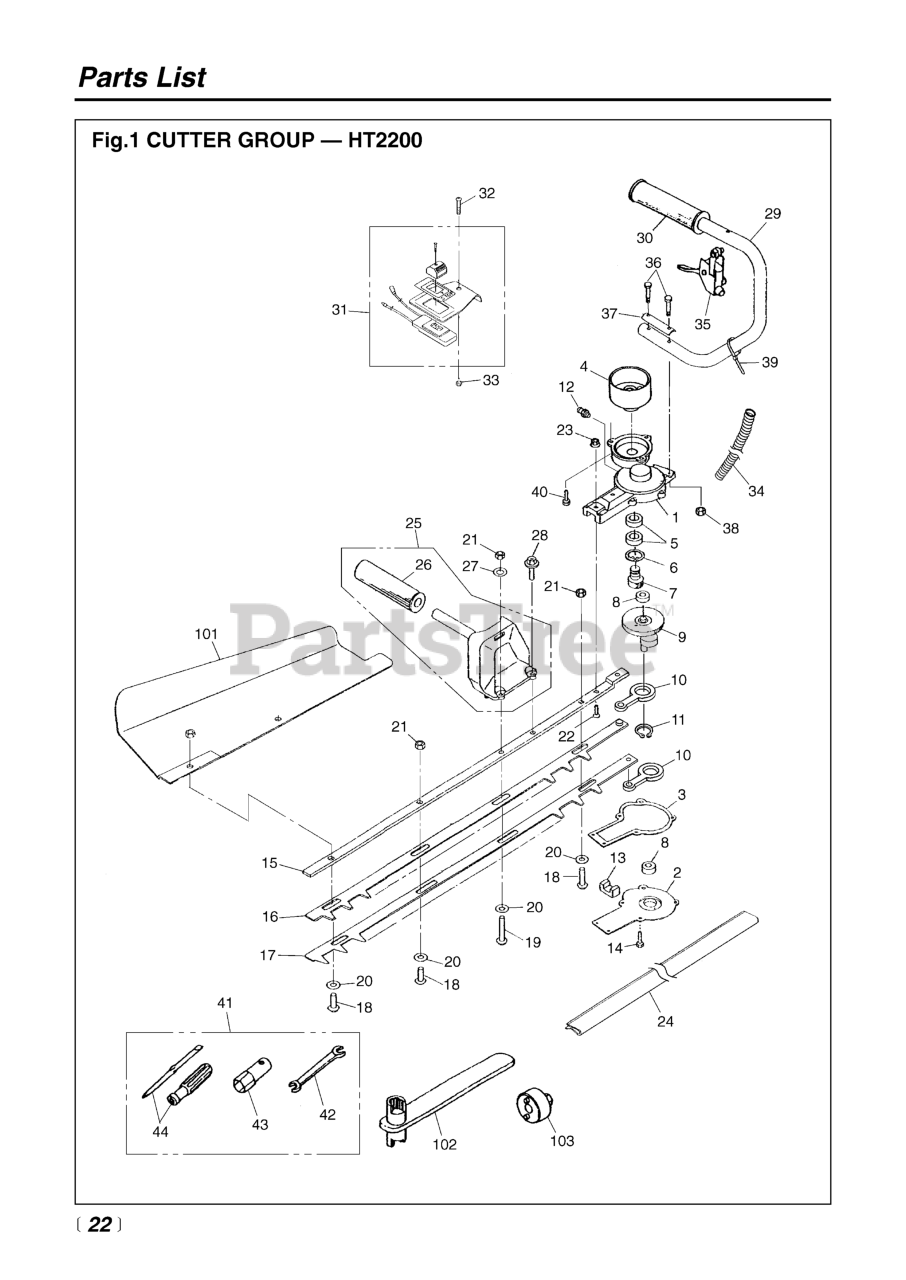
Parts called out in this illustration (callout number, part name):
1	GEARCASE
2	COVER
3	GASKET
4	DRUM, CLUTCH
5	BEARING
6	RING, SNAP
7	PINION
9	GEAR COMPL
10	ROD
11	RING, SNAP, M25 X 1.2
12	FITTING, GREASE
13	FELT
14	BOLT
15	PLATE, GUIDE
16	BLADE, UPPER
17	BLADE, LOWER
20	WASHER (RPLS 3873-11760)
21	NUT, M6
22	SCREW
23	NUT
24	COVER, BLADE
25	HANDLE COMPL
26	GRIP (RPLS -13120)
28	BOLT
29	HANDLE COMP.
30	GRIP (RPLS -13120)
31	SWITCH
33	NUT, M5 X 4
34	TUBE
35	LEVER ASSEMBLY
36	BOLT, M5x25 (RPLS -50520)
38	NUT (RPLS 3873-14470)
39	BAND, CABLE
40	BOLT, M6 X 14
41	TOOL SET
42	SPANNER, 8 X 10 (RPLS 2540- )
43	SOCKET, HEX, 3/4
44	SCREWDRIVER
101	RECEIVE PLATE
103	WRENCH (TOOL)
